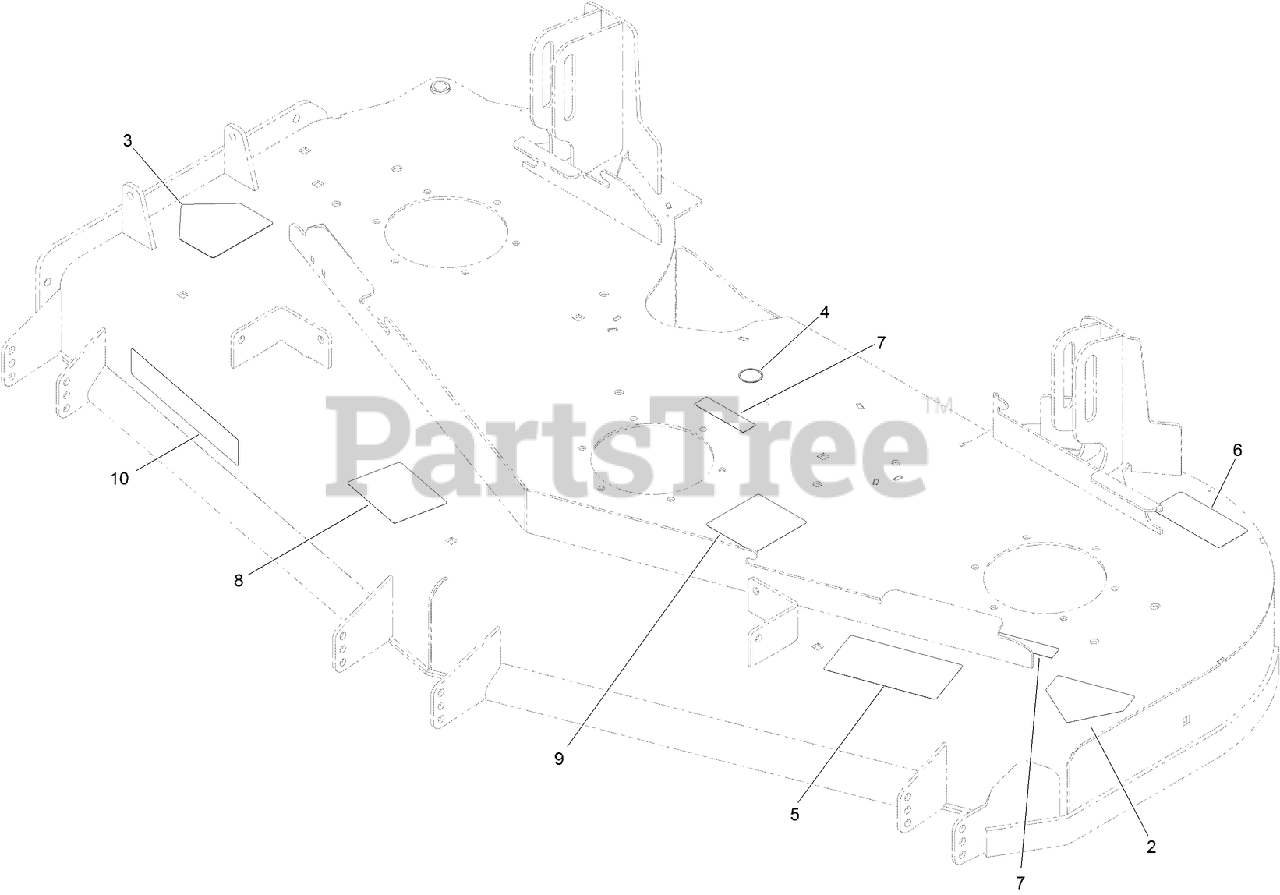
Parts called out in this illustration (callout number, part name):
2	DECAL-DANGER
3	DECAL-DANGER
4	DECAL-GREASE
5	DECAL-DANGER, THROWN OBJECT
6	DECAL-TORQUE
7	DECAL-COVER, MISSING
8	DECAL-SCALP, ANTI
9	DECAL-ROUTING, DECK BELT
